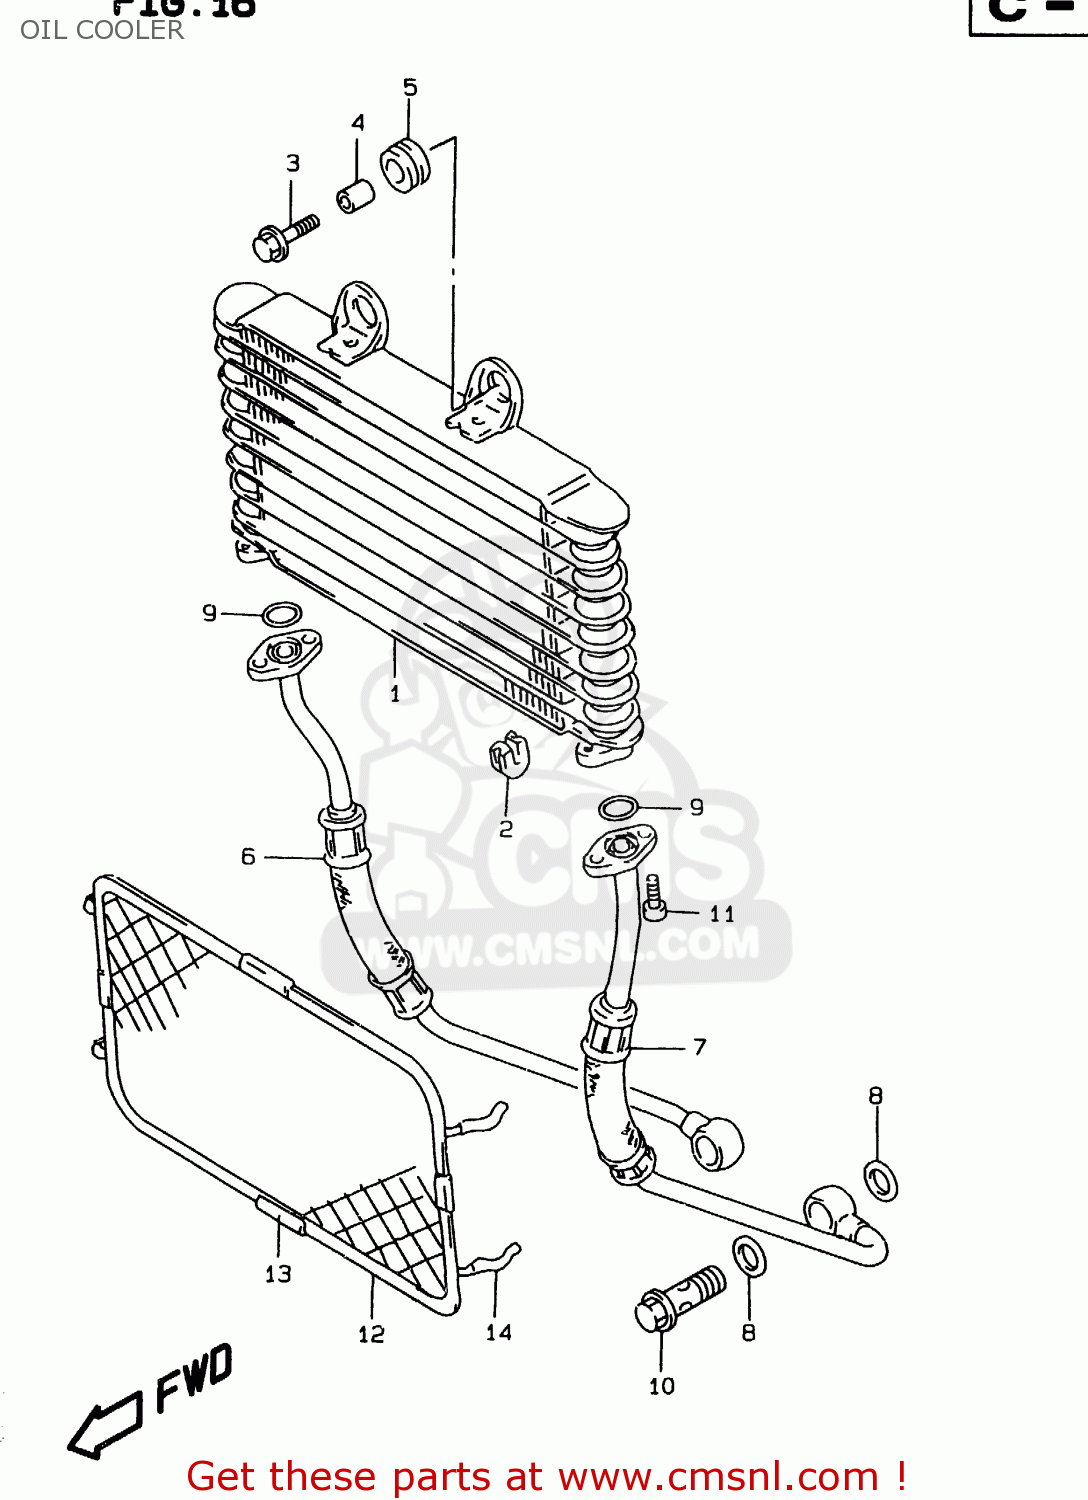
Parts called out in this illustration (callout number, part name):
1	COOLER ASSY,OIL
2	CUSHION,OIL COOLER NO.2
3	BOLT 6X20
4	SPACER(6.5X10X10)
5	CUSHION
6	HOSE,OIL COOLER,R
7	HOSE COMP,OIL COOLER,LEFT
8	GASKET(16X22X2) (NAS)
9	O RING(D:2.4,ID:12.3)
10	BOLT UNION
11	BOLT
12	GUARD,OIL COOLER
13	PROTECTOR,CTR
14	HOSE(3X5X600)
